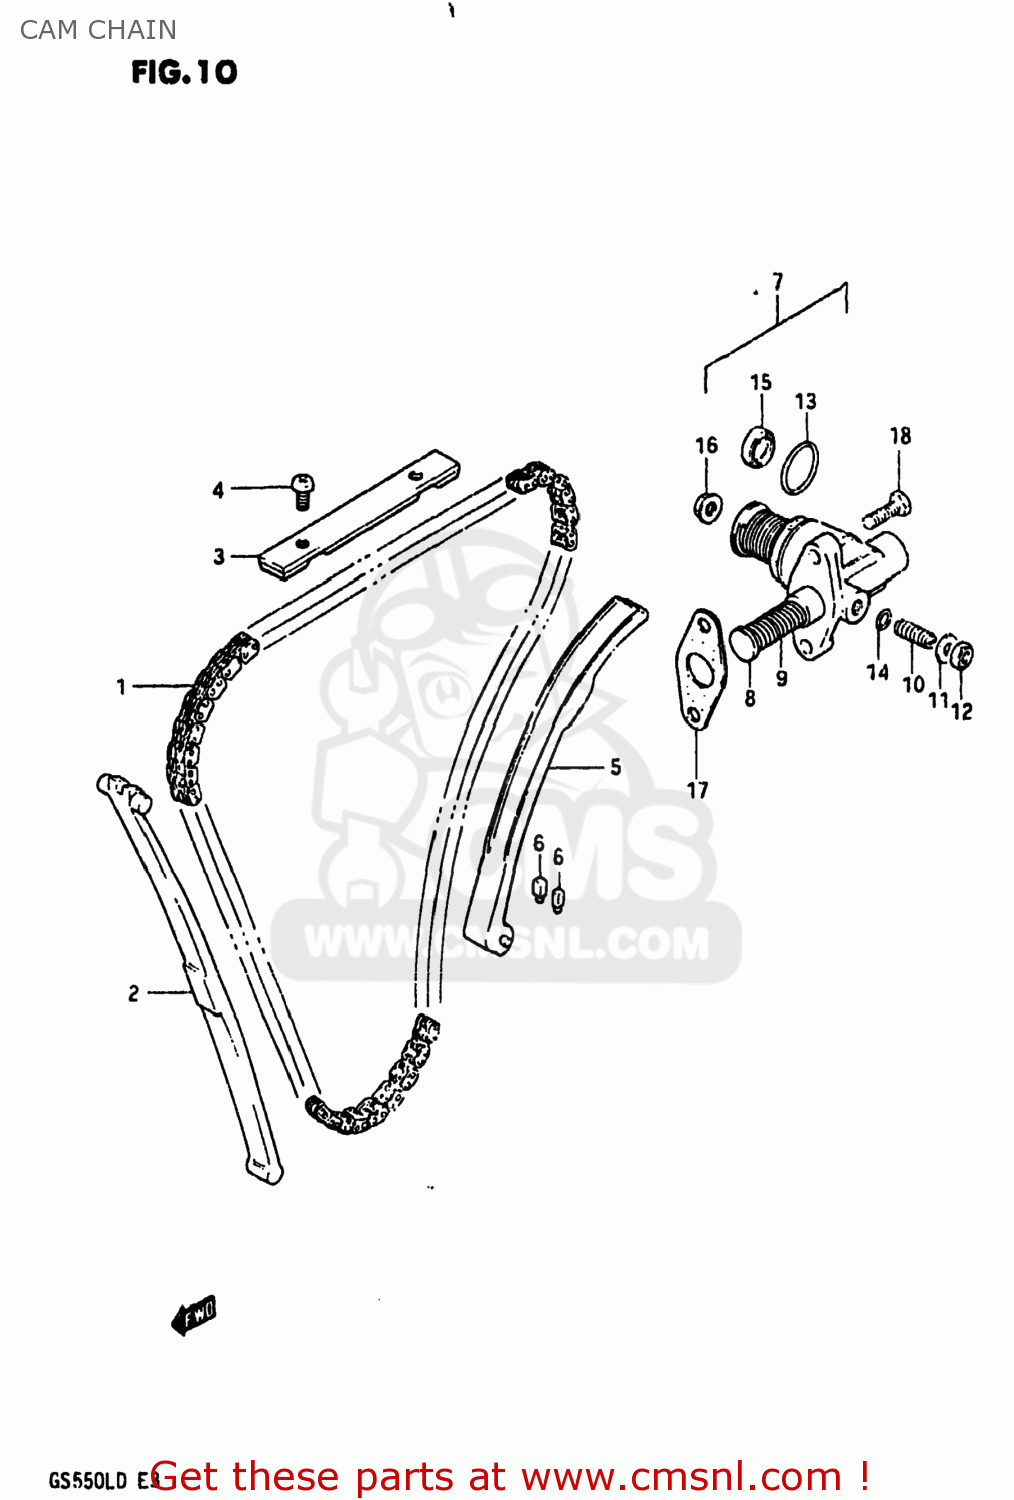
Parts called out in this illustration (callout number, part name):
1	CHAIN,CAMSHAFT DRIVE
2	GUIDE,CAM CHAIN NO.1
3	GUIDE,CAM CHAIN NO.2
4	SCREW
5	TENSIONER,CAM CHAIN
6	CUSHION,CAM CHAIN TENSIONER
7	ADJUSTER ASSY,TENSIONER
8	ROD,PUSH
9	SPRING
10	SCREW,TENSIONER ADJUST
11	WASHER,8.5X16X
12	NUT
13	O-RING
14	O-RING
15	OIL SEAL
16	NUT
17	GASKET,TENSIONER ADJUSTER (MCA)
18	SCREW
